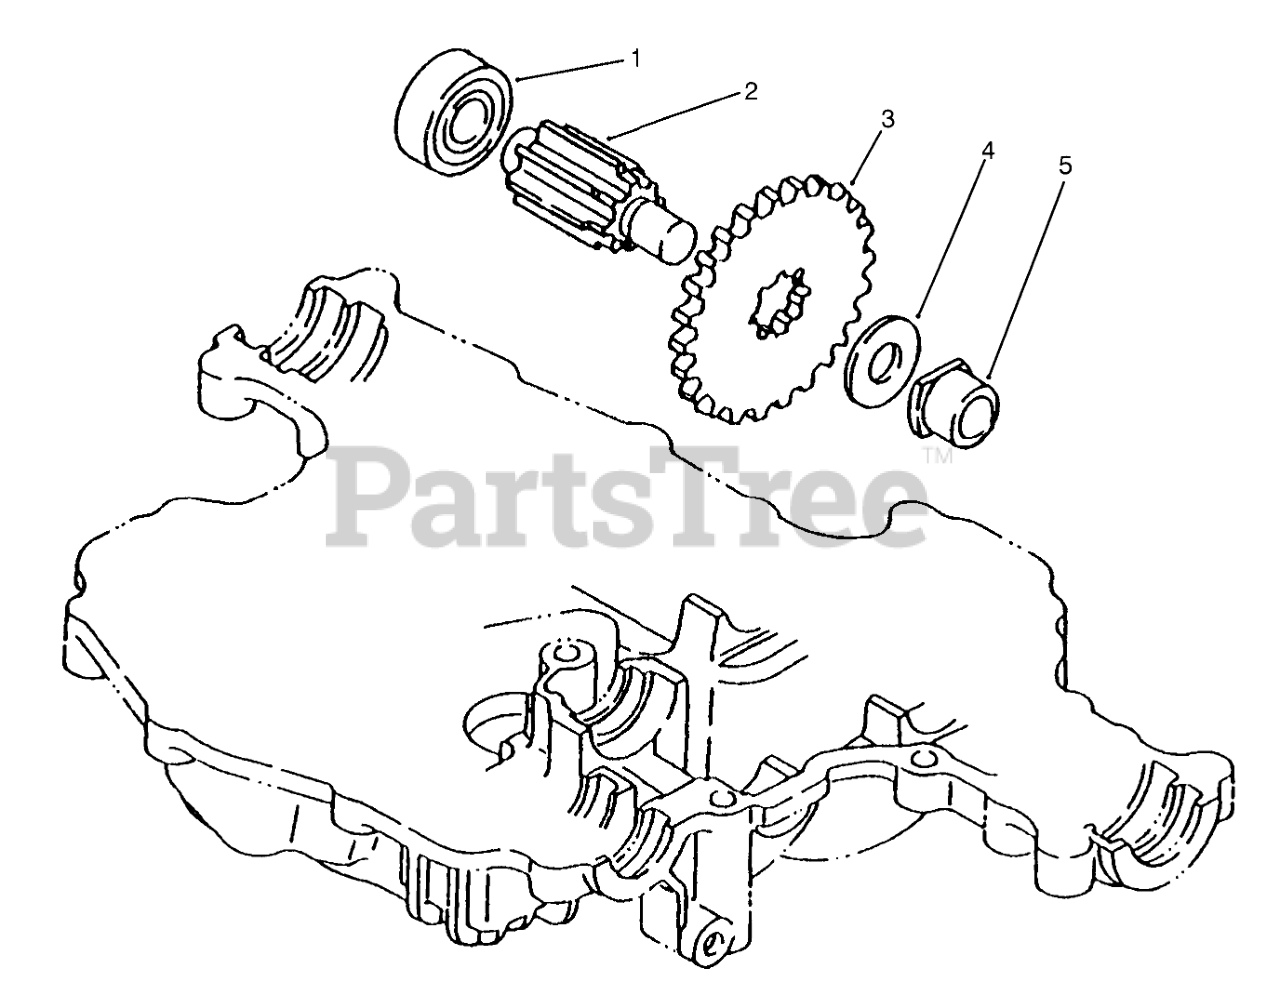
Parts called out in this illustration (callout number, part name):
1	Bearing (Only On: 72043,72063,72103)
2	Shaft-Final Pinion (Only On: 72043,72063,72103)
3	Gear-Final Shaft (Only On: 72043,72063,72103)
4	Washer (Only On: 72043,72063,72103)
5	Bushing (Only On: 72043,72063,72103)
